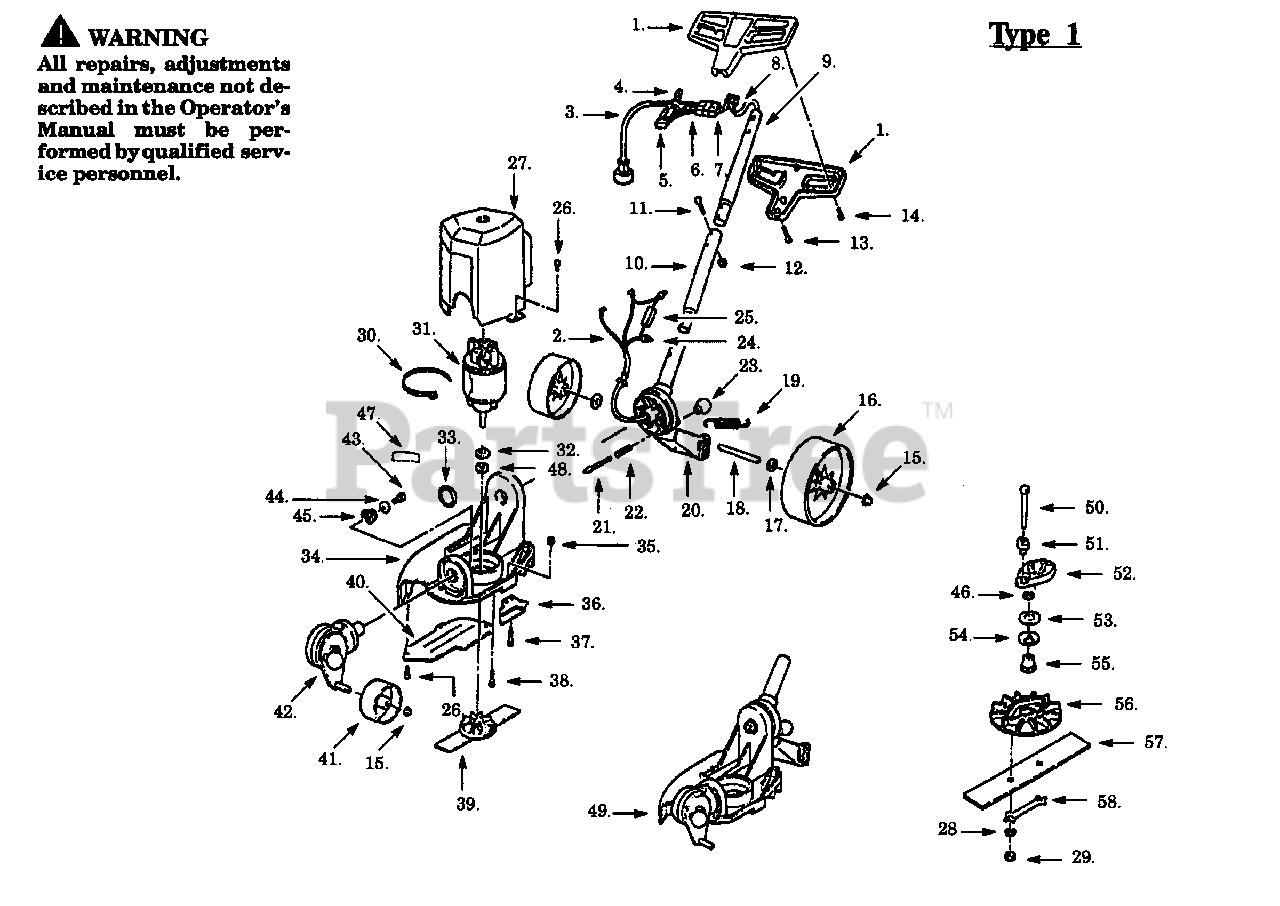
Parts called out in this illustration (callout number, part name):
1	Handle Set
2	Harness Ass'y.
3	Power Cord
4	Wire Nut
6	Bridge Ass'y., Model E125BT
6	Bridge Ass'y., Model E150BT
7	Insulator Shield
8	Harness Ass'y., Model E125BT
8	Harness Ass'y., Model E150BT
9	Upper Tube
10	Lower Tube
12	Locknut
15	Push Nut
16	Rear Wheel
18	Rear Axle
20	Rear Swivel
21	Swivel Lock Shaft
22	Swivel Lock Spring
24	Terminal Cap
25	Resister
27	Motor Cover
28	Lockwasher
30	Tie Wrap
31	Motor Ass'y., Model E125BT
31	Motor Ass'y., Model E150BT
33	Retaining Ring
34	Deck Frame
36	Blade Guide
39	Blade Ass'y.
40	Side Guard Plate
41	Front Wheel
42	Front Swivel Ass'y.
45	Front Swivel Spring
47	Warning Label, Model E125BT
47	Warning Label, Model E150BT
49	Edger Frame Ass'y.
51	Insulating Sleeve
52	Clutch Plate
54	Spring Washer
55	Clutch Sleeve
58	Lock Strap
